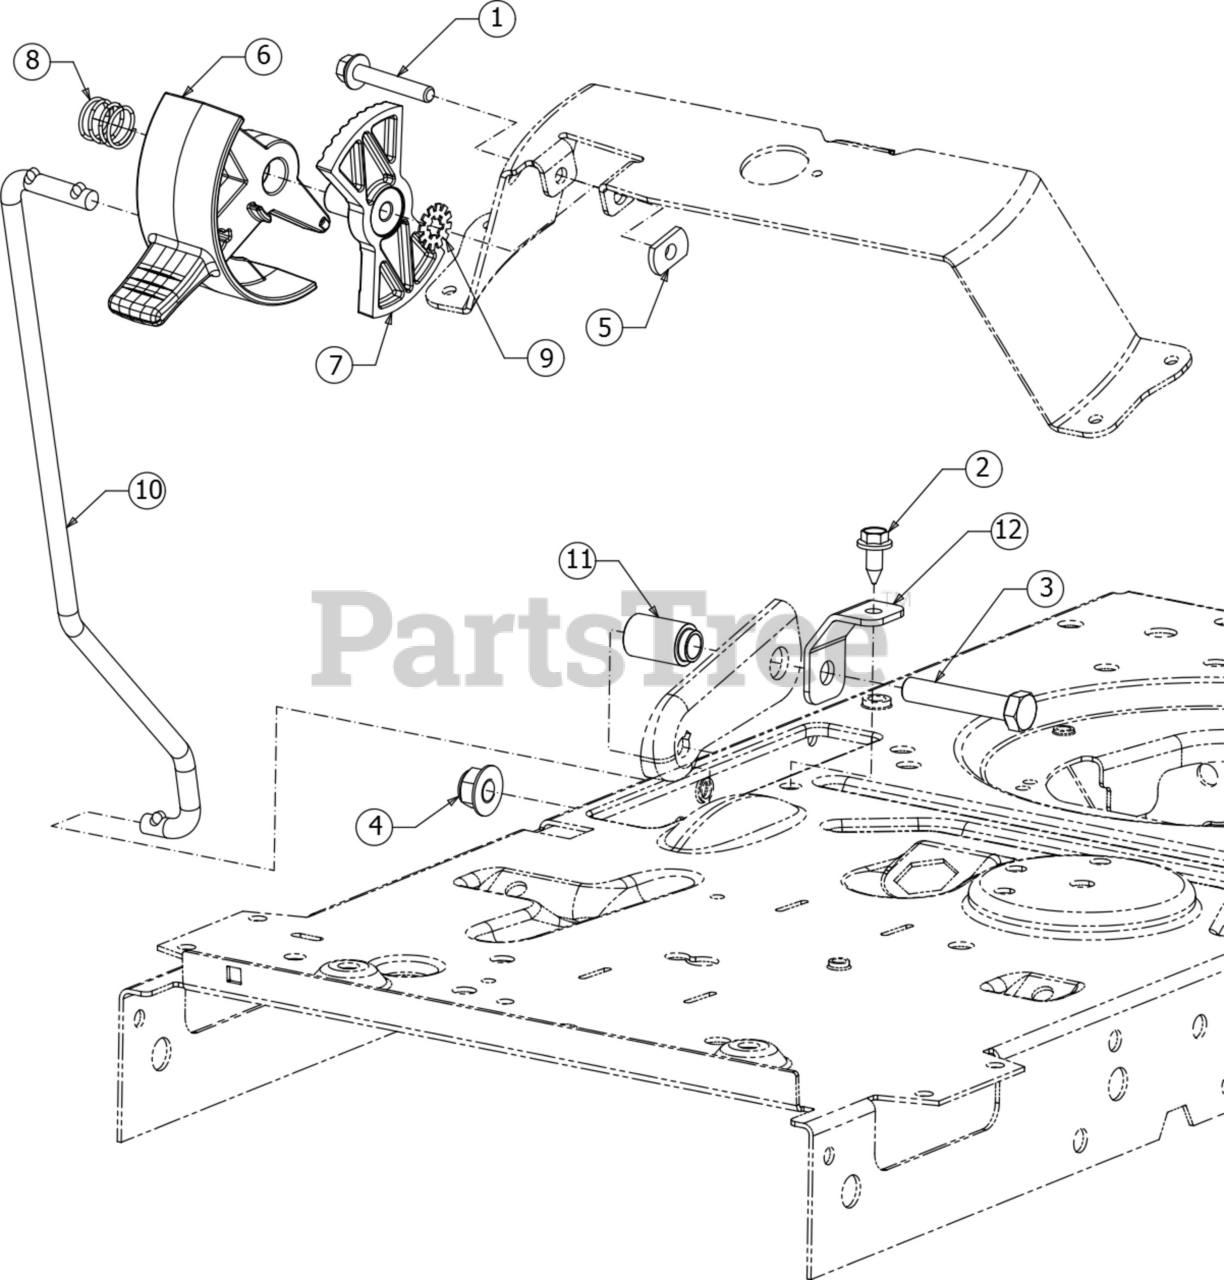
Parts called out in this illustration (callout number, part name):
1	SCREW 1/4-20 X 1.50 GR5
2	SCREW 1/4-20X.625
3	SCREW 3/8-16 X 2.0 GR5
5	FLAT NUT
6	SHIFT LEVER
7	INDEX CONTROL 7SPEED
8	COMPRESSION SPRING
9	WASHER
10	SPEED CONTROL ROD
11	FLANGE SPACER
12	SPEED LATCH TAB
